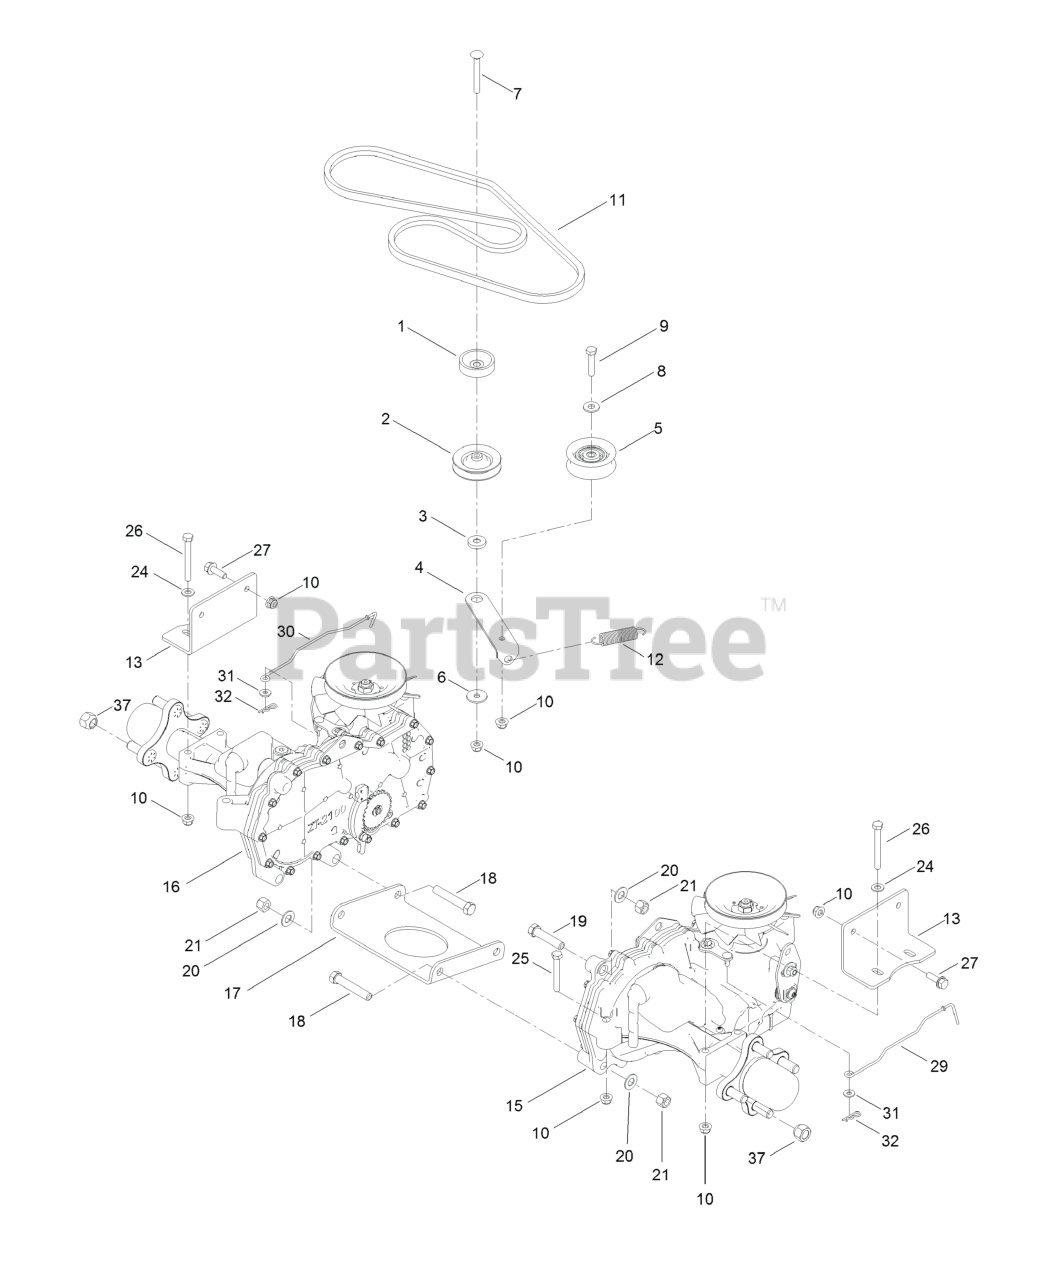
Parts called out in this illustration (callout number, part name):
2	PULLEY-IDLER
3	SPACER-ARM, IDLER
4	Arm-Idler
5	Pulley-Idler, Flat
6	WASHER-PIVOT
7	SCREW-CARR
8	WASHER-FLAT
9	SCREW-HH
10	NUT-HF, NI
11	V-BELT
12	Spring-Return, Pedal
13	MOUNT-HYDRO
15	LH HYDRO TRANSAXLE ASM
16	RH HYDRO TRANSAXLE ASM
17	PLATE-CROSS, HYDRO
18	SCREW-HH
19	SCREW-HH
20	WASHER-FLAT
21	NUT-LOCK, NI
24	WASHER-PLAIN
25	SCREW-HH
26	SCREW-HH
27	SCREW-HHF
29	Rod- Bypass,LH
30	Rod- Bypass,RH
37	NUT-LUG
